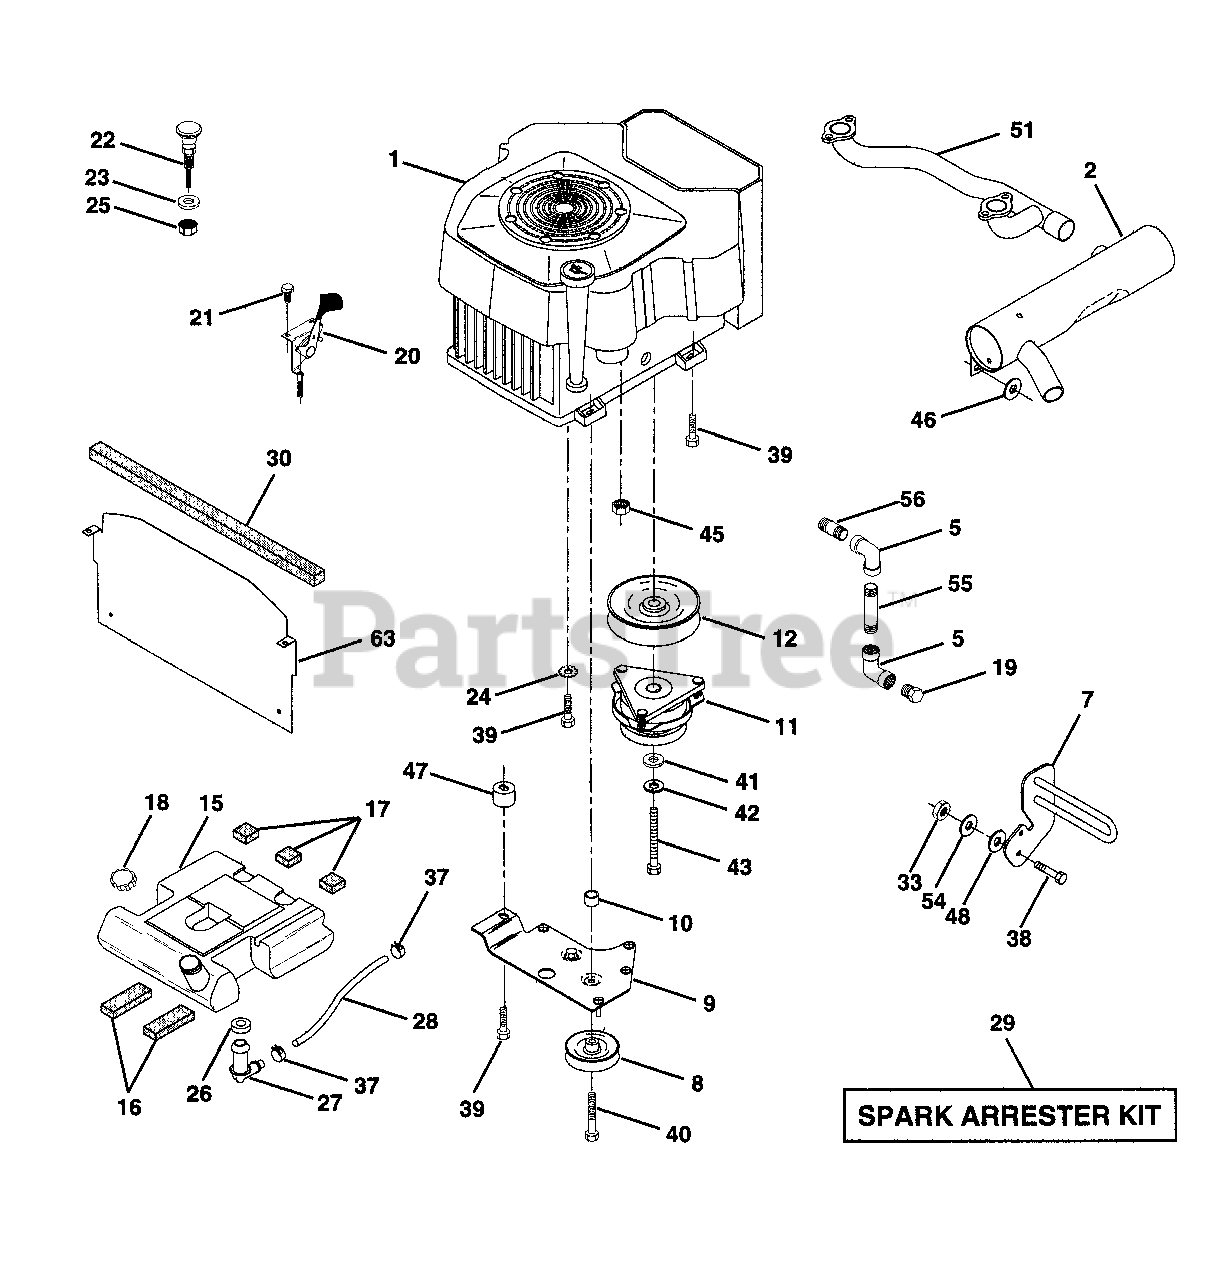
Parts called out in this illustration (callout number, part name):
2	Muffler VGT Cylinder
5	Elbow STD 90 Degree 3/8-18 NPT
7	Muffler Assembly Guard
8	Pulley V-Idler
9	Keeper Asm Belt Engine VGT 96
11	Clutch Electric
12	Pulley Engine VGT Elect Clutch
15	Tank Fuel Rear
16	Pad Spacer
17	Pad Spacer
18	Cap Asm Fuel W/Sym Vented
19	Plug Oil Drain
20	Control Throttle
21	Screw Hex Thd Cut 1/4-20 X 5/8
22	Control Choke
23	Washer 13/32 X 13/16 x 16 Ga
24	Washer Ext Tooth 3/8
25	Nut Keps 3/8 - 24 UNF
26	Bushing
27	Stem Tank Fuel
28	Fuel Line
29	Spark Arrester Kit
30	Strip Foam 18"
33	Nut, Hex W/Ins. 3/8-16 UNC
37	Clamp Hose
38	Bolt, Fin Hex 3/8-16 UNC x 1-1/2
39	Screw TT 3/8-16 x 2-1/4 UNC
40	Screw TT 3/8-16 x 4 UNC
41	Washer 1-1/2 OD X 15/32 ID X .250
42	Washer Lock 7/16
43	Bolt Hex 7/16-20 X 4-1 /4 Ga 5
45	Nut Flange 1/4-20 Starter Nut
46	Washer 13/32 x 1 x 16 Ga.
47	Spacer Engine
48	Washer 13/32 x 1-1/4 x 7 Ga.
51	Pipe Crossover
54	Washer Flat 13/32 x 7/8 x 14 Ga.
55	Nipple, Pipe 3/8 NPT x 4-1/2
56	Nipple, Pipe 3/8 NPT x 1.00
63	Shield, Heat VGT YP/Husq.
